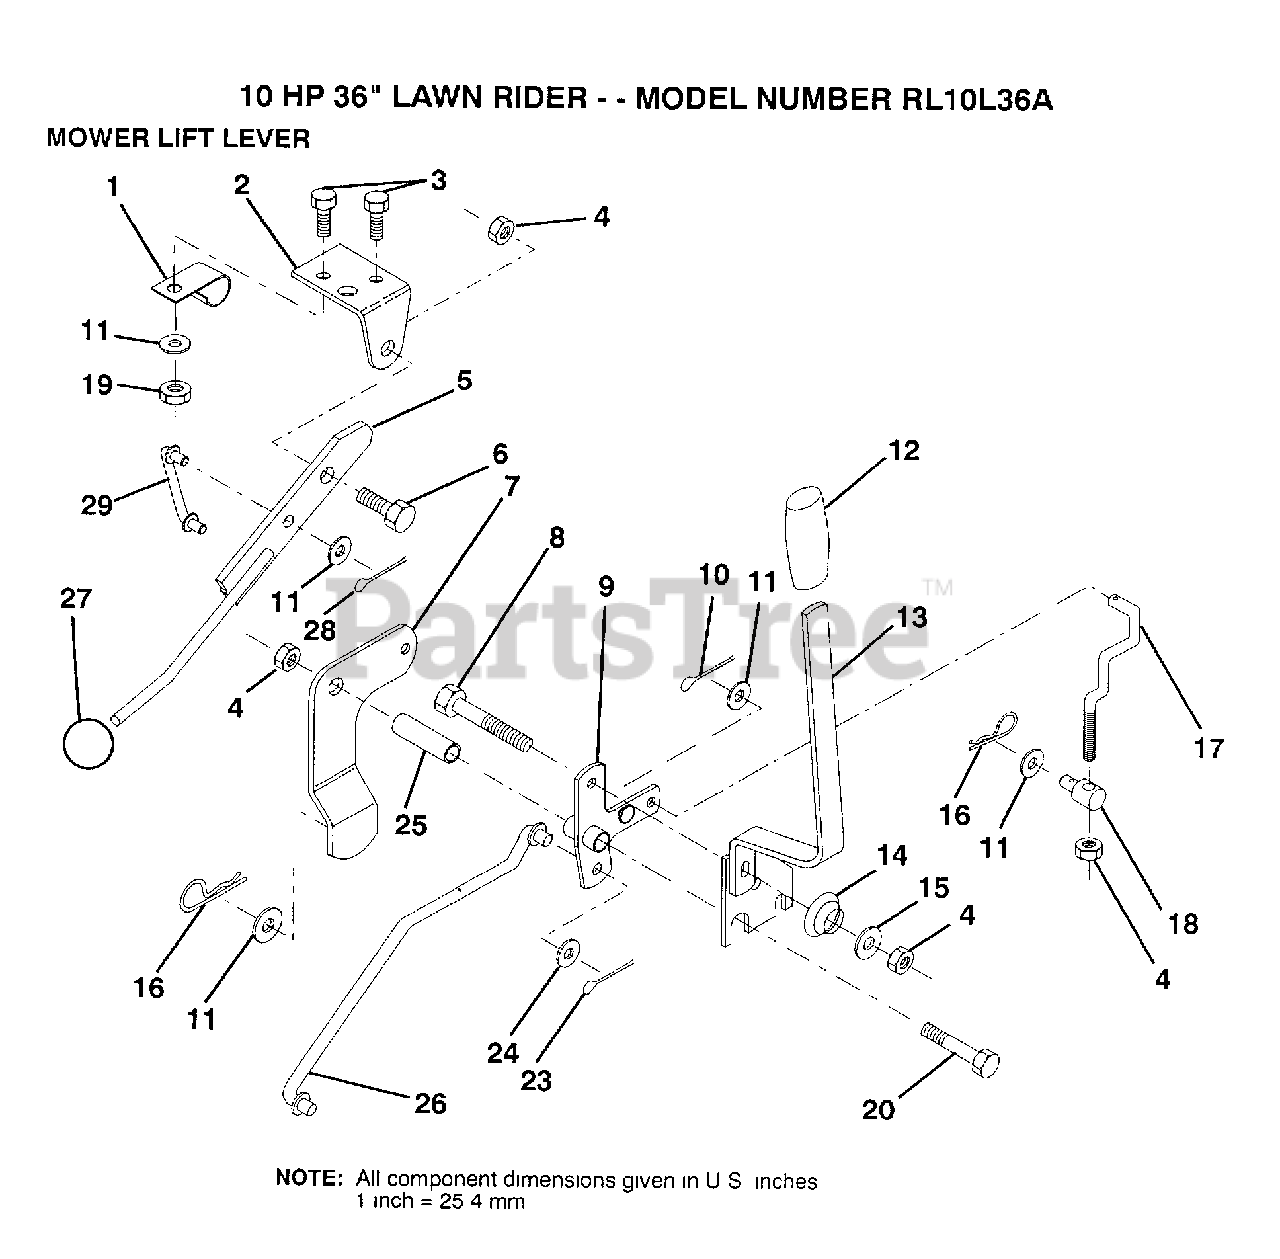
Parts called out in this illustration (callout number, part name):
1	"CLIP,INSULATOR"
2	BRKT CLUTCH
3	BOLT
5	CLUTCH LEVER AS
6	"BOLT, SHOULDER LT"
7	MWR CLUTCH ARM AS
8	BOLT
9	"BELLCRANK,LIFT"
10	COTTER PIN
11	WASHER
13	"HDLE,LIFT T"
14	SPRING COMPRESSIO
15	WASHER T
16	SPRING.RETAINER
17	"LINK,LIFT FRT"
18	TRUNION
20	BOLT
23	PIN COTTER 1/8
25	TUBE SPACER
26	"ROD,MOWER LIFT "
27	KNOB T(3/8 HOLE)
29	CLUTCH LINK
